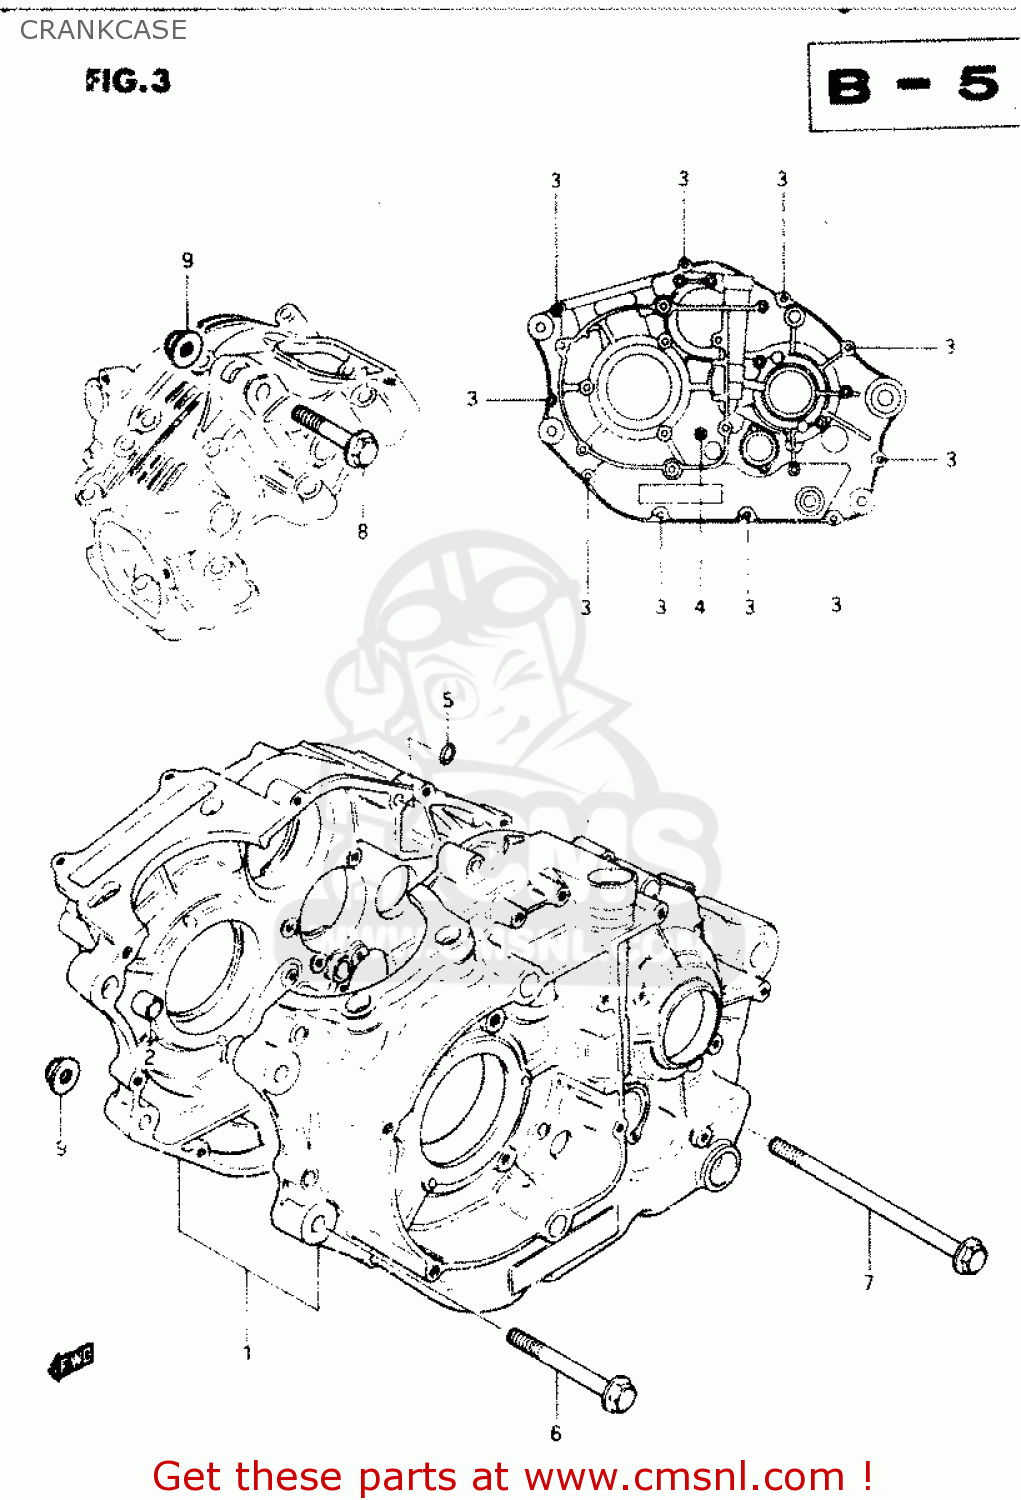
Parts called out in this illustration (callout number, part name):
1	CRANKCASE ASSEMBLY
2	PIN
3	BOLT (6X35)
4	BOLT (6X55)
5	O-RING
6	BOLT 8X67
7	BOLT
8	BOLT 8X50
9	NUT
